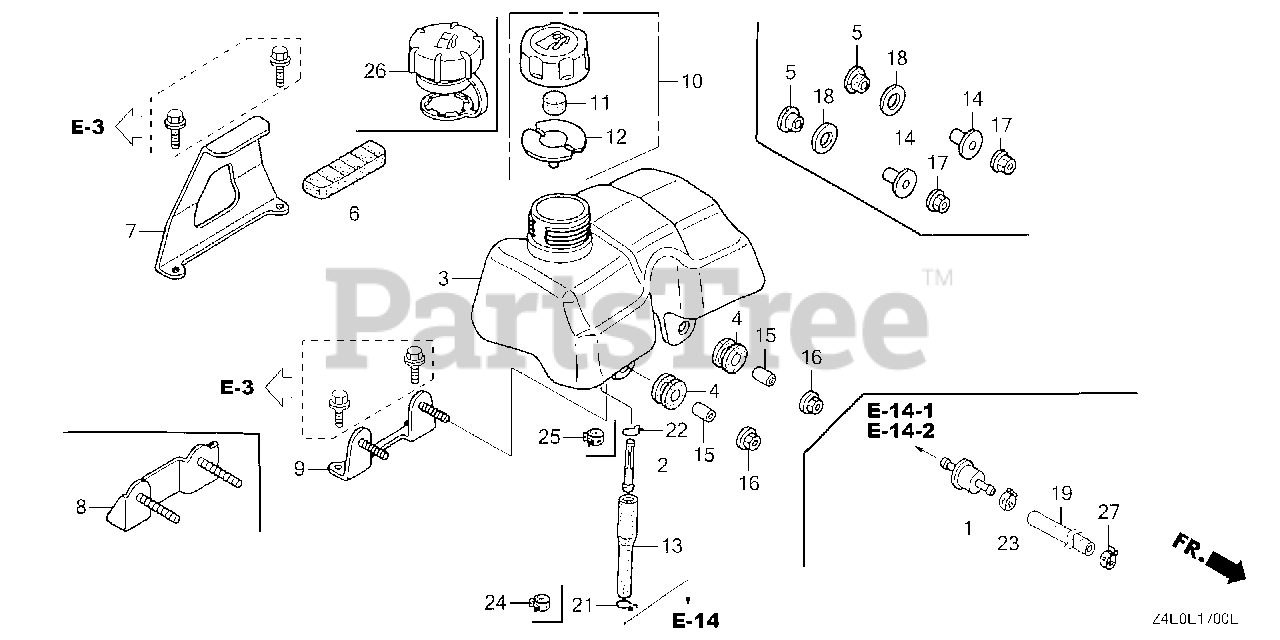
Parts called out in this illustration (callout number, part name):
2	FILTER, FUEL
3	TANK, FUEL
5	RUBBER A, TANK MOUNTING
6	RUBBER B, TANK MOUNTING
7	STAY A, FUEL TANK
8	STAY B, FUEL TANK
10	CAP ASSY., FUEL TANK
11	SPONGE, FUEL CAP BREATHER
12	GASKET, FUEL CAP
13	TUBE, FUEL
13	TUBE, FUEL (FKM)
14	COLLAR, CANISTER MOUNTING
17	NUT, SELF-LOCK (6MM)
18	WASHER, PLAIN (15MM)
21	CLIP, TUBE (B8)
22	CLIP, TUBE (B10)
24	CLAMP, TUBE (D8)
25	CLAMP, TUBE (D10.5)
26	CAP ASSY., FUEL TANK
